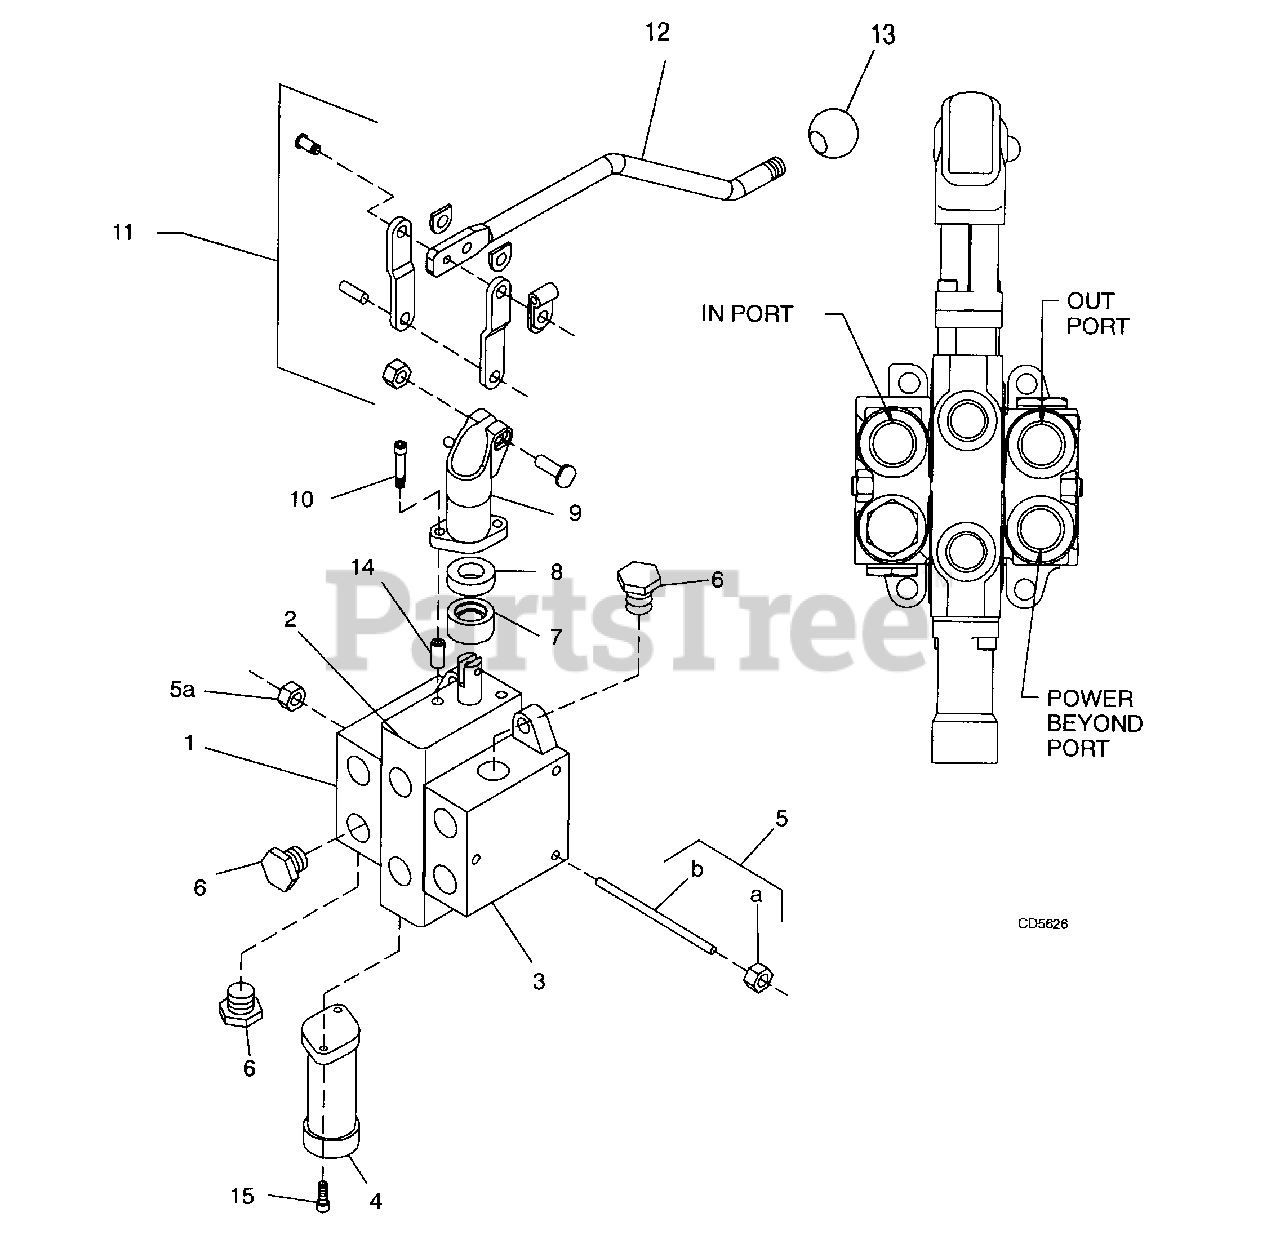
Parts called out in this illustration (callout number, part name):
1	Valve inlet section
2	Spool section
3	Valve outlet section
4	Spool float repair kit
5	Valve spool tie rod kit
5A	UNKOWN
5B	UNKOWN
6	Inlet plug assembly
7	Valve spool repair sleeve
8	Valve spool seal plate
9	Handle bracket
10	1/4-20 UNC x 1-3/4 Socket head cap screw
11	Handle service kit
12	Valve spool bent handle
13	1/2 NC x 1.88 diameter knob
14	Valve spool handle spacer
15	1/4-20 UNC x 3/4 Socket head cap screw
